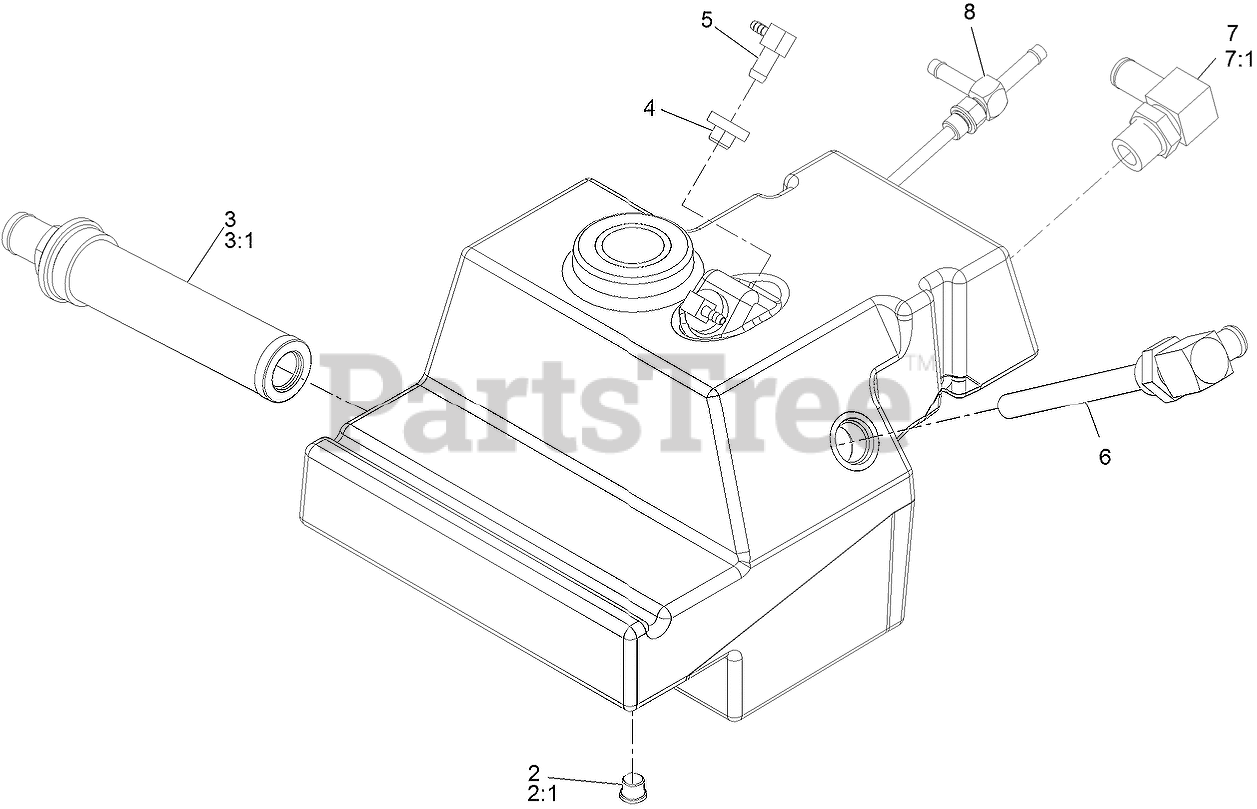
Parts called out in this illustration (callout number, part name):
2	PLUG-HEX, HOLLOW
2:1	O-RING
3	TANK STRAINER ASM
4	BUSHING
5	FITTING-ELBOW, 90 DEG
6	Fitting-Standpipe
7	FITTING-ELBOW, 90
7:1	O-RING
8	FITTING-TEE, DROP TUBE
